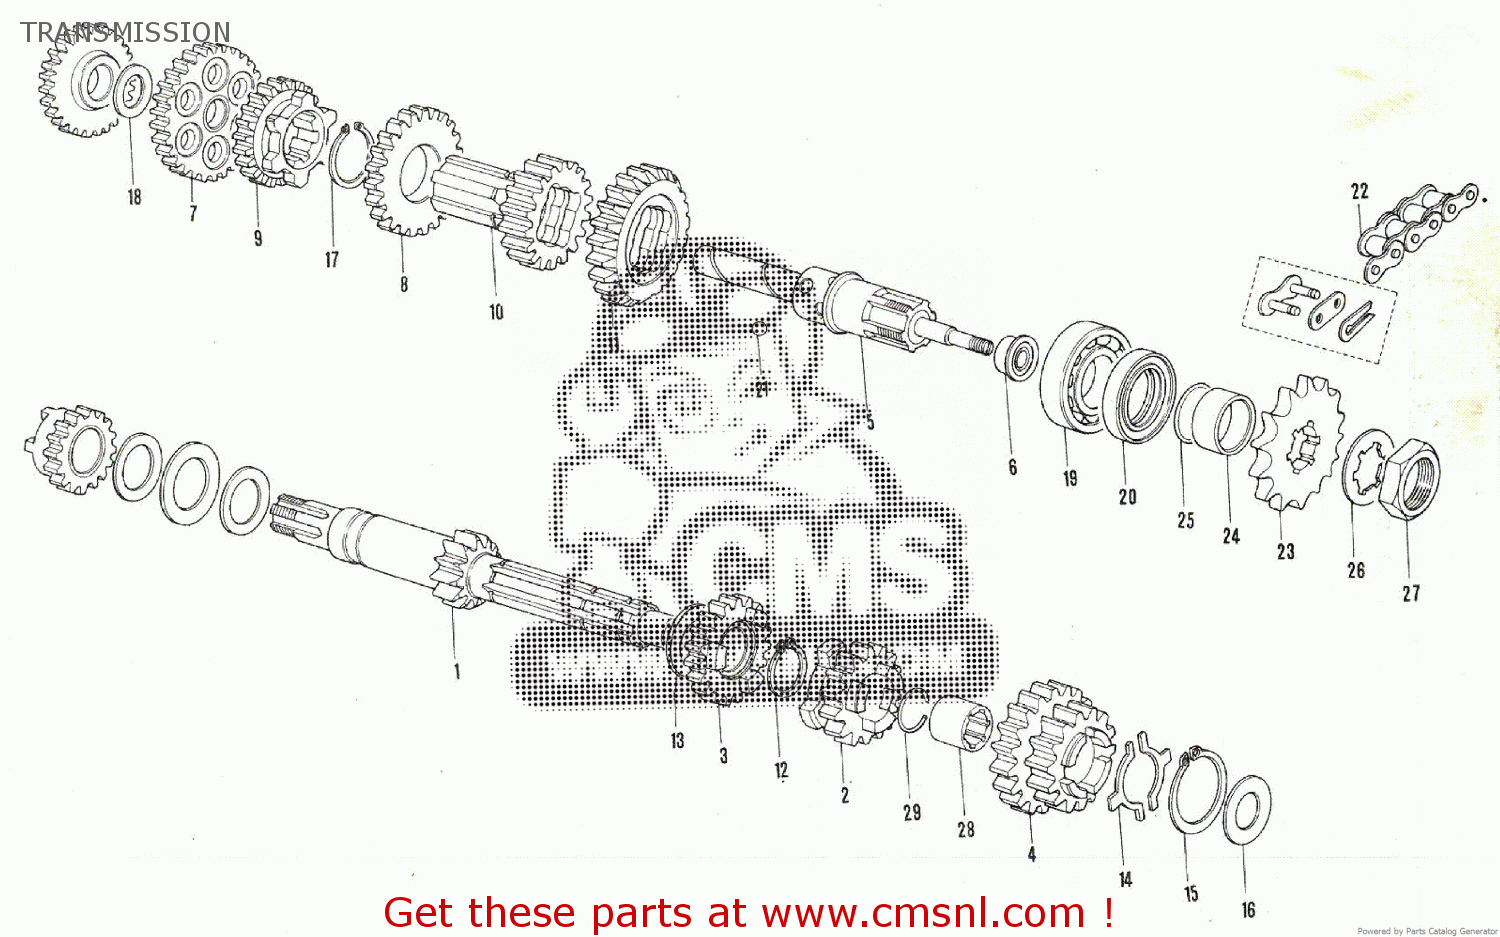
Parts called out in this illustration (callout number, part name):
1	SHAFT,COUNTER
2	GEAR,SECOND DRIVE
3	GEAR,THIRD DRIVE
4	GEAR,FOURTH DRIVE
5	SHAFT,DRIVE
6	OIL SEAL
7	GEAR,FIRST DRIVEN
8	GEAR,SECOND DRIVEN
9	GEAR,THIRD DRIVEN
10	GEAR,FOURTH DRIVEN
11	5TH DRIVEN GEAR
12	CIRCLIP
13	WASHER
14	KNOCK RING
15	RING,SNAP
16	WASHER
17	RING,SNAP
18	WASHER
19	BEARING
20	SEAL,OIL(30X44X6)
21	BALL
22	CHAIN ASSEMBLY,DRIVE
23	SPROCKET,ENGINE
24	SPACER ENGINE SPROCKET 25X30X13.5
25	O RING(D:1,ID:24.5)
26	WASHER
27	NUT
28	BUSHING,FOURTH DRIVE GEAR
29	CIRCLIP
